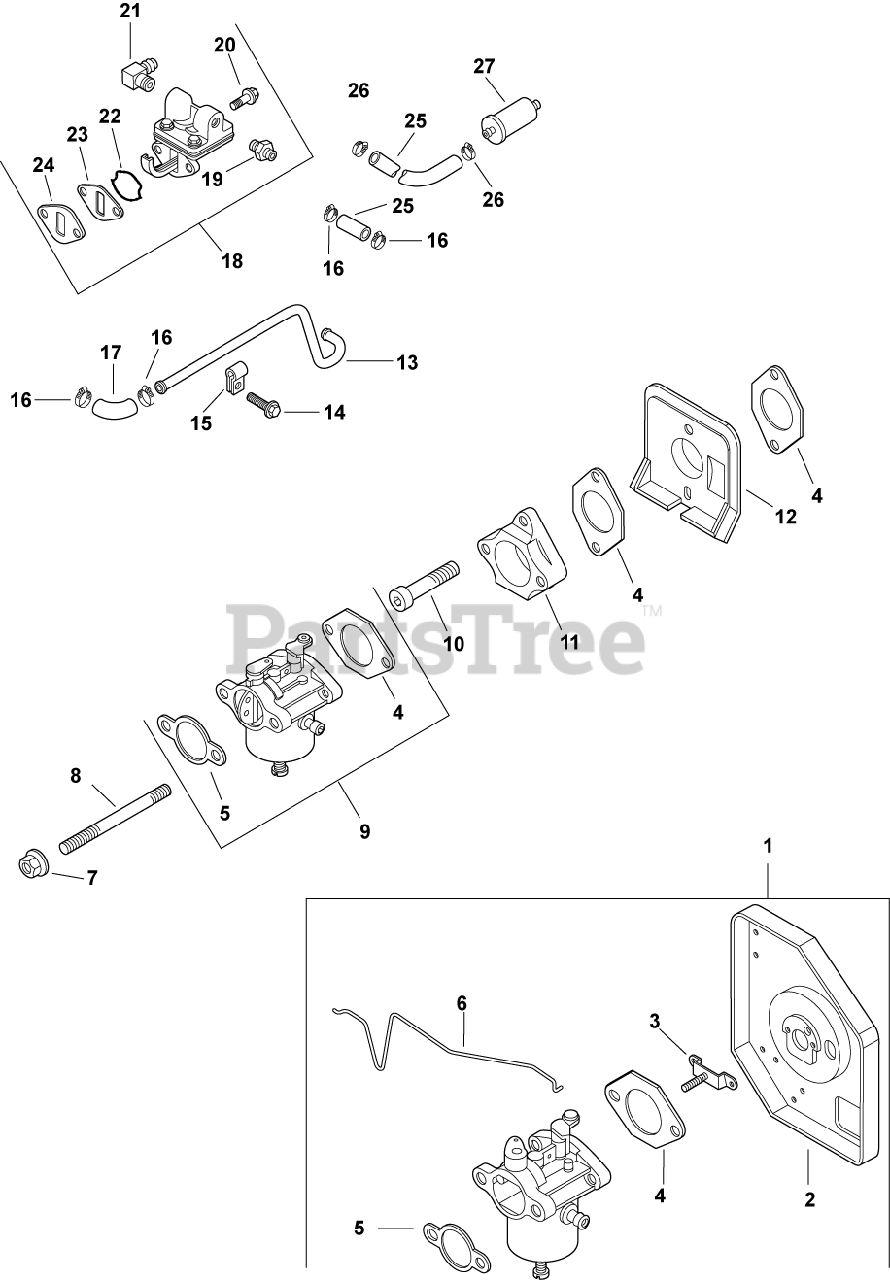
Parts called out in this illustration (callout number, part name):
1	KIT, CARB. RETROFIT
2	BASE, AIR CLEANER
3	BRACKET, AIR CLEANER
4	GASKET, CARBURETOR
5	GASKET, AIR CLEANER BASE
6	LINKAGE, CHOKE
7	NUT, FLG M6X1.0
8	STUD,M6X1.0X116
9	KIT, CARBURETOR
10	SCREW, SKT CAP M6X1.0X35
11	ADAPTER, CARBURETOR
12	DEFLECTOR, HEAT
13	LINE, FUEL - DISCONTINUED
14	SCREW, FLG THD FRM M5X.8X10
15	CLIP, TUBE & WIRING (KM)
16	CLAMP, HOSE (KM)-USE 25 237 31-S
17	HOSE, FUEL LOW-PERMEATION
18	KIT, FUEL PUMP
19	KIT, STRAIGHT FITTING
20	SCREW,FLG THD FRM M6X1.0X20-(#25086396S)
21	CONNECTOR, 90 DEG. HOSE
22	O-RING, FUEL PUMP
23	SPACER, FUEL PUMP
24	GASKET, FUEL PUMP
25	HOSE,LW PERM.FUEL 24.00"-USE 25 111 81-S
26	CLAMP, BAND SPRING HOSE-(#2523737S)
27	FILTER,FUEL 51 MICRON (FUEL PUMP)
2514106-S	TOOL, INSTALLATION (SNAP RING)
M-664020-S	SCREW, LBD SKT M6x1.0x20-(#25086403S)
